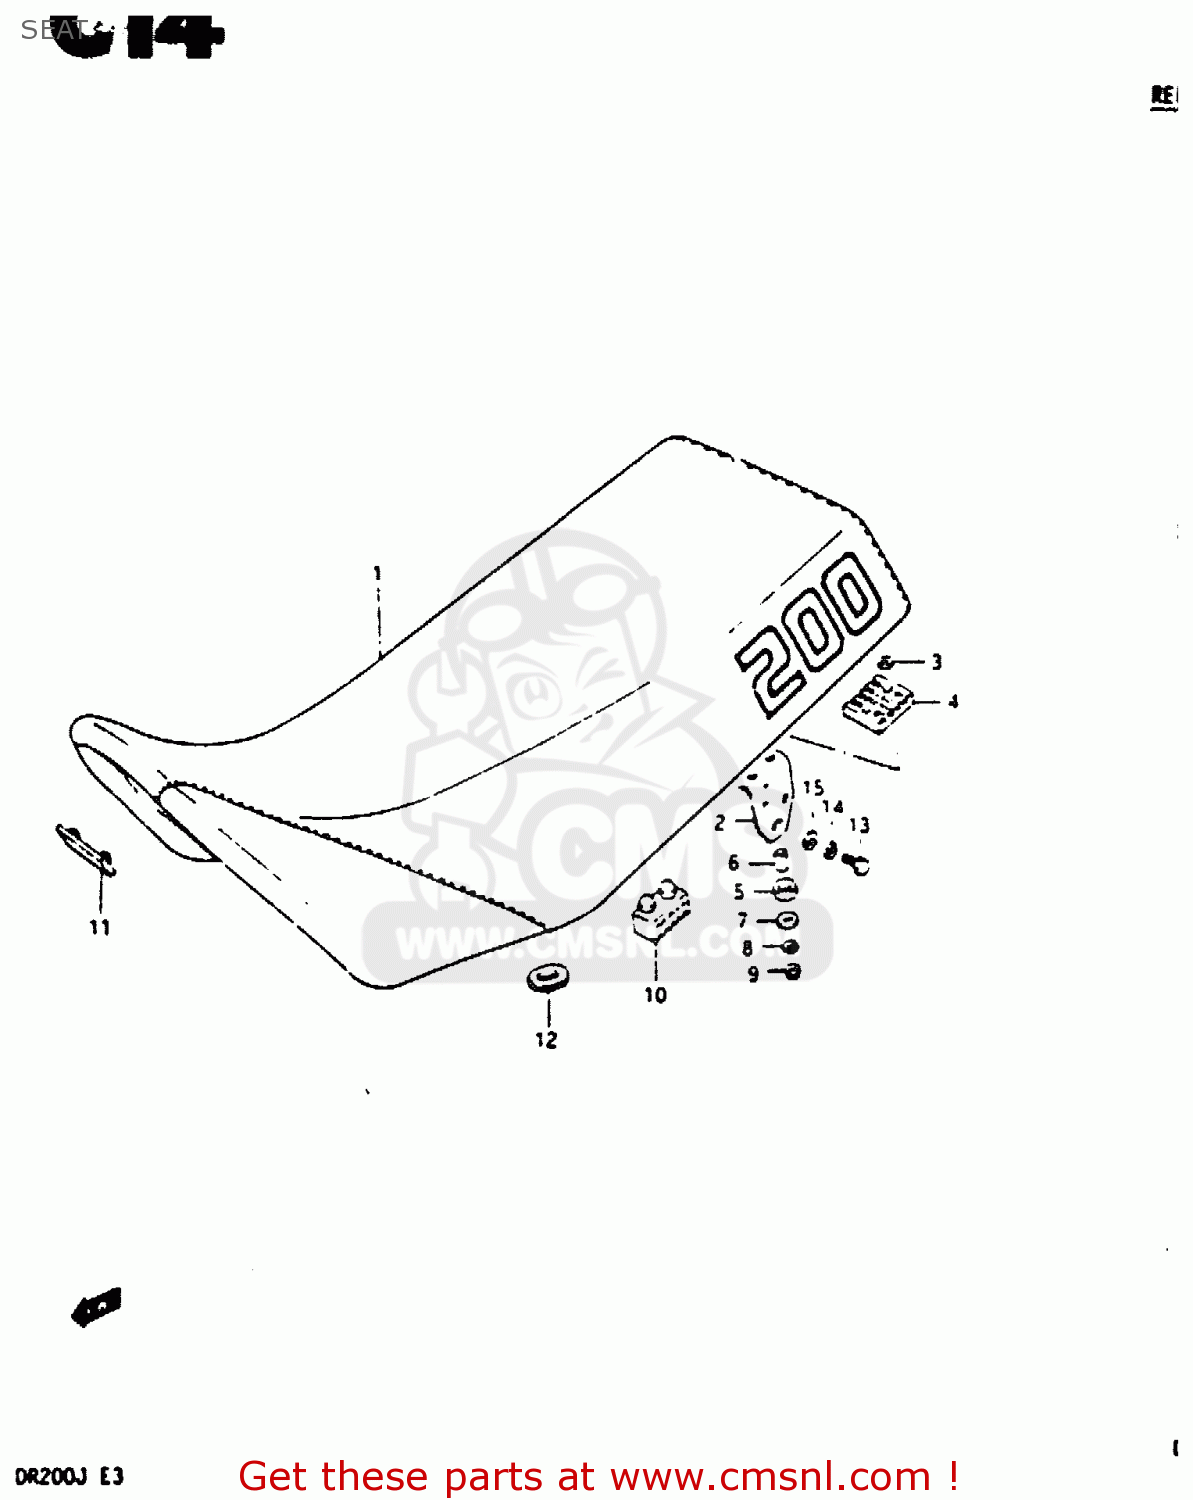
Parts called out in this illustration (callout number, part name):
1	SEAT ASSEMBLY
2	BRACKET,LEFT
3	WASHER, LOWER
4	CUSHION,FR PLATE
5	CUSHION,SEAT FR
6	SPACER,SEAT SUPPORT
7	WASHER
8	WASHER,LOCK
9	NUT
10	CUSHION,SEAT(40X20X15)
11	CUSHION
12	CUSHION
13	BOLT
14	WASHER,LOCK,8.
15	WASHER
